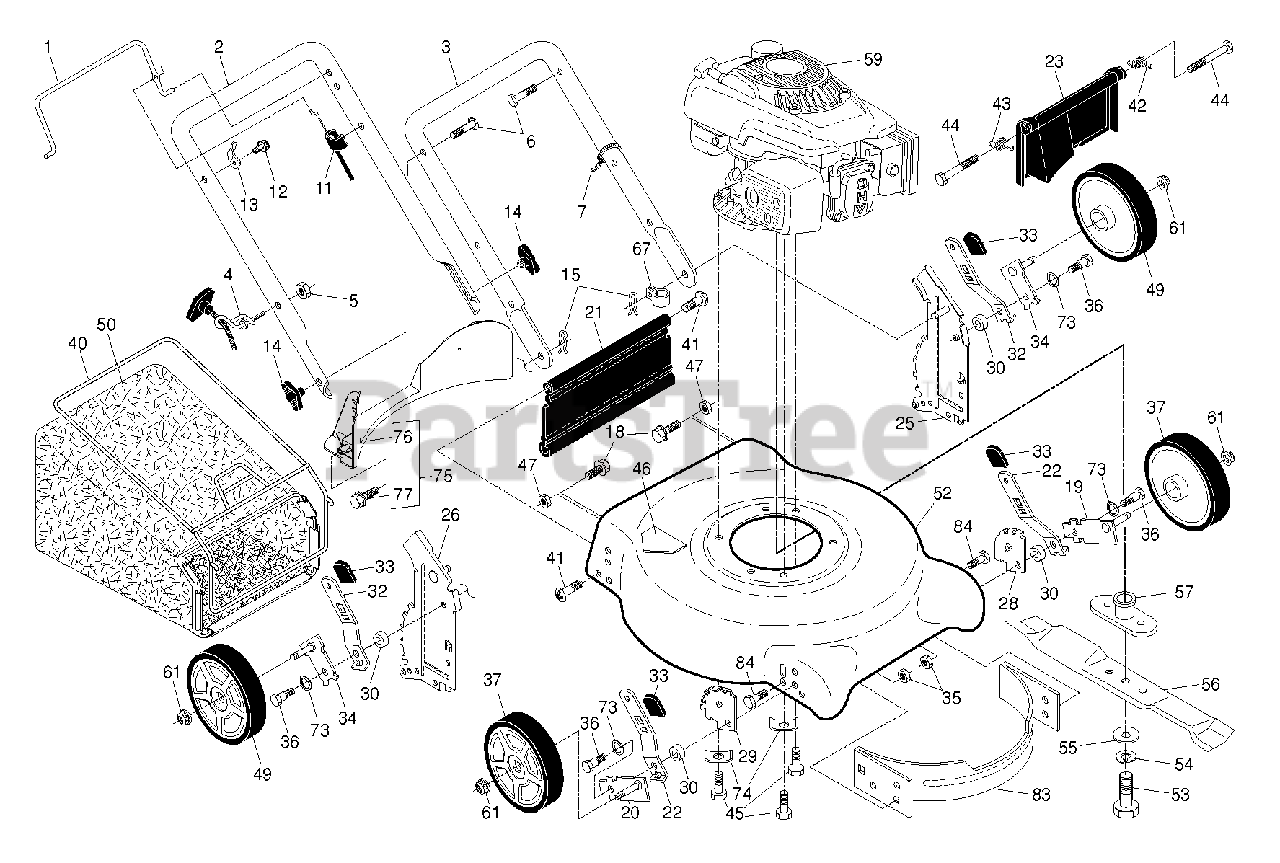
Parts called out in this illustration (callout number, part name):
1	BAIL.CONT.D.STRAIGHT.PUSH.BLK
2	HANDLE.UPPER.ECONOMY.BLACK
3	HANDLE.LOWER.D-STRAIT.BLACK
4	GUIDE.ROPE.STD.BLK.ZIN
5	NUT
6	BOLT, HANDLE 5/16-18X1.75
7	TIE GUIDE
11	CABLE.MZR.RATO.22"LOW.
13	BRACKET.UPSTOP.RT
14	KNOB.WING.PLASTIC.BLACK
15	HAIRPIN COTTER
18	SCREW 1/4X20
19	AXLE ARM ASSY FRONT LH
20	AXLE ARM ASSY FRONT RH
21	KIT.SKIRT.21 DOMED.W/LIP
22	SELECTOR SPRING, FRONT
23	REAR DOOR ASSY
25	RP BRACKET.ASM.HANDLE.LH.LW.BL
26	RP BRACKET.ASM.HANDLE.RH.LW.BL
28	BRACKET.ADJ.5.RTAB.LG.HOLE.ABS
29	BRACKET.ADJ.5.LTAB.LG.HOLE.ABS
30	SPACER.HEIGHT.ADJUSTER
32	SPRING.SELECTOR.21RD.HTTRT.BZP
34	ARM.ASM.AXLE.REAR.5/9.POS.BZP
35	NUT.FLANGE.HEX.5/16X18.BLACK
36	SHOULDER BOLT 5/16-18
37	WHEEL.7X1.75.5SPK.BRK.MARG.1
40	FRAME.BAG.21.REAR.DOMED.PUSH
41	SCREW.1/4-20X21/4.HEX.
42	SPRING.LH.22.REAR.DOOR.EZ.EMPT
43	SPRING.RH.22.REAR.DOOR.EZ.
45	BOLT 3/8-16X1-1/8
46	No Step Decal
47	NUT.CENTERLOCK.5/16-
52	HOUSING.21RD.DOME.GRE
53	BOLT.3/8-24X1.25 GR8
55	WASHER,HARDEN
56	BLADE.21.PUSH/RWGD/FWGD
57	ADAPTER.BLADE.W/KEY.25MM.CE
59	ENGINE.RATO.550S.140C
61	NUT.HEX.FLANGE.3/8-16.LOCKNUT
73	WASHER.CURVED.CYLINDRICAL
74	WASHER.ENGINE.BZP
75	KIT.BAFFLE.REAR.PLASTIC.21.RD
76	BAFFLE.REAR.PLASTIC.21.RD.ECON
77	SCREW.HX.13X.750
83	BAFFLE.FRONT.21.DOME.US
84	BOLT.5/16HEX.WHS.HD
